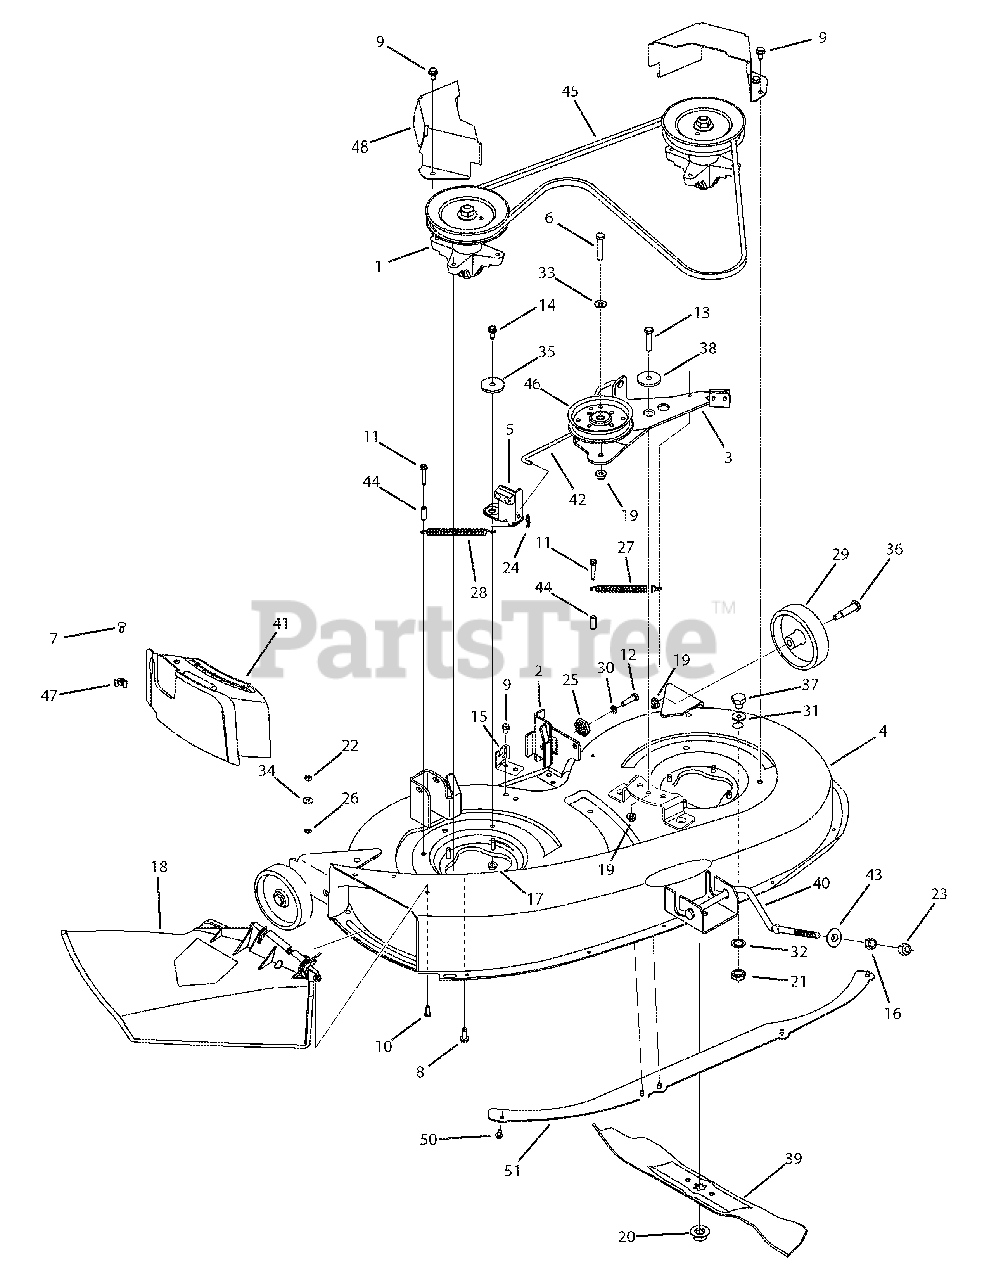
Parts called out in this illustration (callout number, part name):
1	Spindle Assembly, Pul, 5.75" Dia
6	Screw, 3/8-16, 1.75, Gr5
7	Carriage Screw, , 1/4-20 x .62
8	Screw, 5/16-18, 0.75
9	Screw, 5/16-18, 0.625
10	Screw, 1/4-20, .75, Gr5
11	Screw, 1/4-20, 1.500
12	Screw, 5/16-18, 1.250
13	Screw, 3/8-16, 1.25, Gr5
14	Screw, 5/16-18, .75, Gr5
16	Nut, Hex, 1/2-13, Gr5
17	Nut, Flange Lock, 5/16-18, GrF
18	Chute Assembly, Discharge
19	Nut, Flange Lock, 3/8-16, GrF
20	Nut, Flange, 5/8-18
21	Nut, Hex, M16-1.5
22	Nut, Hex, 1/4-20, Gr5
23	Nut, Hex Lock, 1/2-13, Gr8, Nylon
24	Pin, Cot, .072 Dia. x 1.13 Lg
25	Gear, Deck Adjustment
26	Nut, Push, .25 ID x .50 OD
27	Spring, Exten. , .75 Dia. x 6.375
28	Spring, Exten. , .50 Dia. x 6.375
29	Wheel, Deck 5.0 x 1.38
30	Washer, Lock, 5/16
31	Washer, Flat, .64 x 1.24 x .06
32	Washer, Lock, 5/8, Internal Tooth
33	Washer, Flat, .406 x .875 x .059
34	Washer, Bell, .265 x.75 x .062
35	Spacer, Shoulder, .5000 x .1475
36	Screw, Shldr, .498 x 1.53, 3/8-16
37	Plug, Screw, M16 x 1.5
38	Spacer, Shoulder, .8840 x .190
39	Blade, 19.38", Star 3-in-1
40	Deck Rod, Front Adjustable
41	Mulch Plug
42	Control Rod, Brake
43	Pivot Cup, Deck Lift
44	Spacer, .260 x .372 x 1.030
45	Belt, V-Type
46	Idler Pulley, 4.25" Dia.
47	Wing Nut, 1/4-20
50	Screw, 1/4-20, .500
